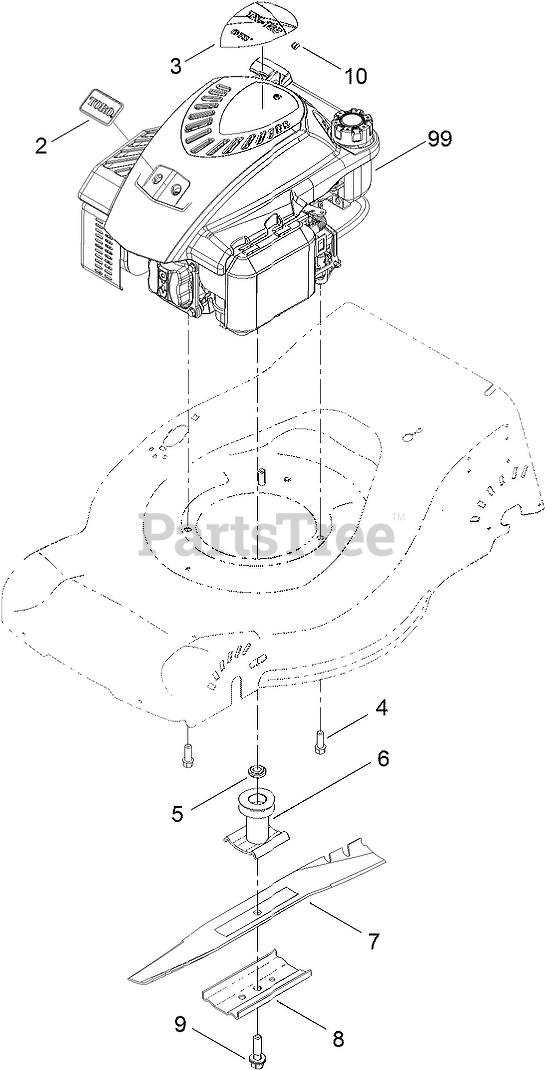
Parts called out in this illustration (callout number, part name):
2	PLATE-LOGO
3	DECAL-SHROUD
4	SCREW-HWH
5	Spacer-Driver
6	DRIVER-BLADE
8	SUPPORT-BLADE
9	BOLT-BLADE
10	STOP-ROPE
99	ENGINE-LC1P65FA
